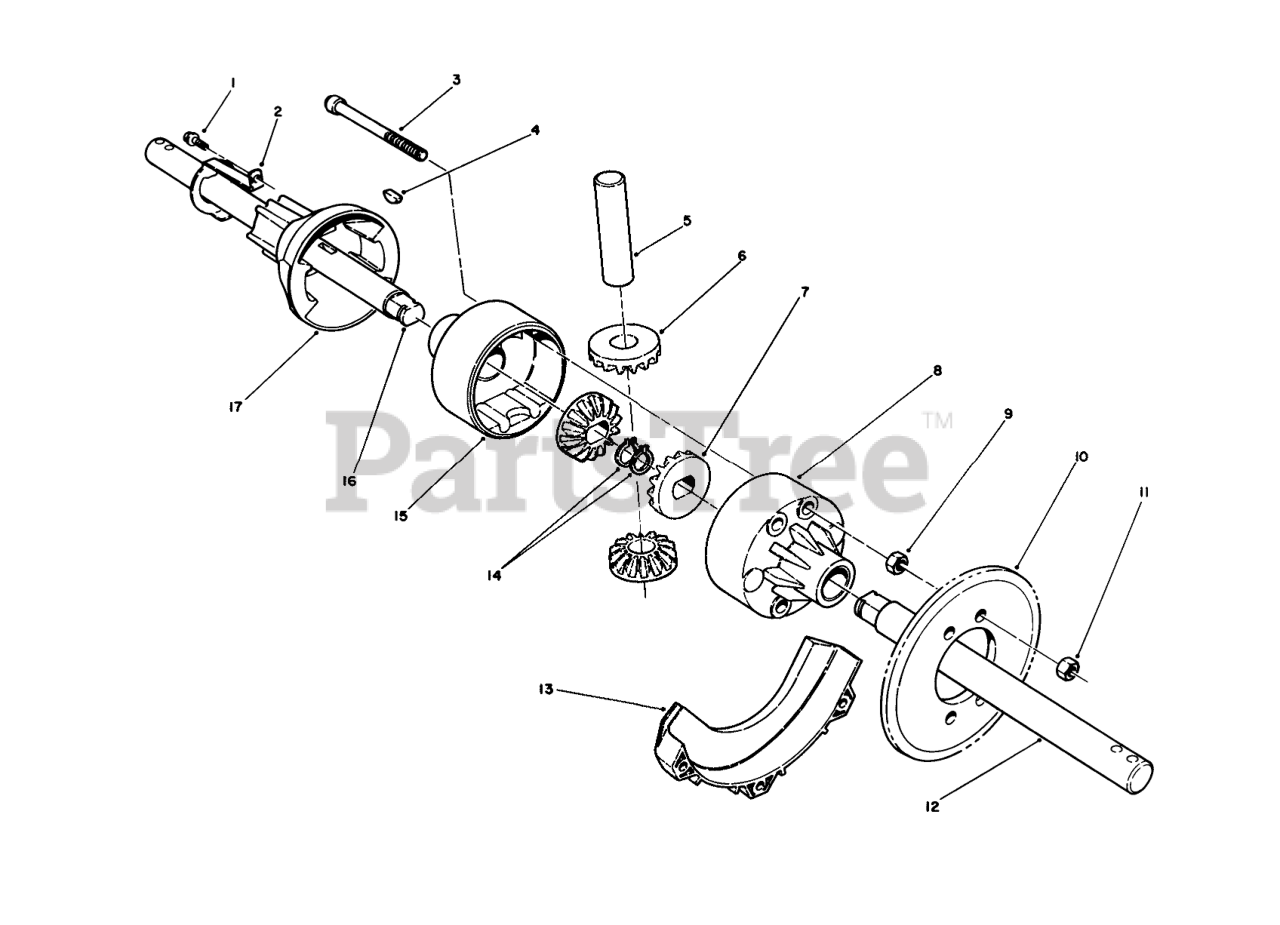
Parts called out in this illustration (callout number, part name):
1	SCREW-HWH
2	SPRING-LOCKOUT
3	SCREW-HSH
4	KEY-WOODRUFF
5	Shaft-Cross
6	Gear-Cross Shaft Pinion
7	Gear-Side Pinion
8	HOUSING ASSY - FEMALE
9	NUT-HEX
10	SPROCKET-27T
11	NUT-LOCK, NI
12	SHAFT - DIFFERENTIAL,LH
13	GUARD-CHAIN
14	RING-RETAINING
15	HOUSING ASSY - MALE
16	SHAFT - DIFFERENTIAL,RH
17	COUPLING-DIFFERENTIAL
